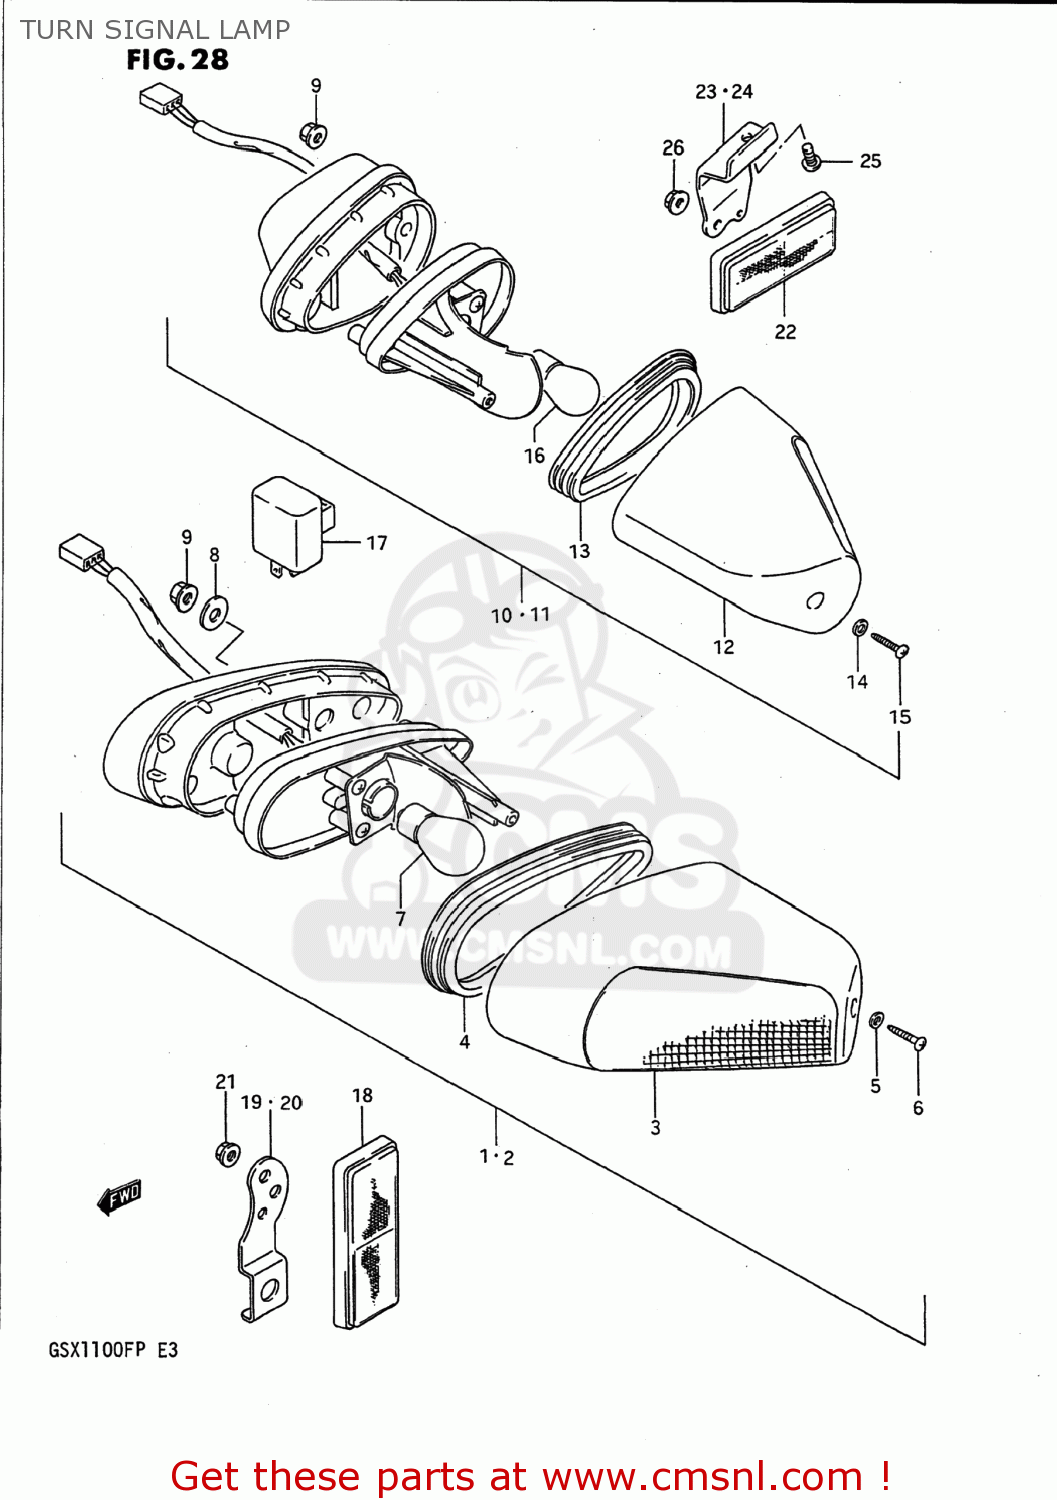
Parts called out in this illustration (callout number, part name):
1	LAMP ASSY,FR TURN SIGNAL,R
2	LAMP ASSY,FR TURN SIGNAL,L
3	LENS
4	GASKET (NAS)
5	GASKET (NAS)
6	SCREW 4X16
7	BULB(12V21/5W)
8	WASHER (6.5X18X1.6)
9	NUT 6MM
10	LAMP ASSEMBLY,REAR TURN SIGNAL
11	LAMP ASSEMBLY,REAR TURN SIGNAL
12	LENS
13	GASKET (NAS)
14	GASKET (NAS)
15	SCREW 4X16
16	BULB(12V21W)
17	RELAY ASSEMBLY,TURN SIGNAL
18	REFLEX REFLECTOR,FR SIDE
19	BRACKET,FRONT SIDE,REAR
20	BRACKET,FR SIDE RR,L
21	NUT ,5MM
22	REFLEX REFLECTOR,RR
23	BRACKET,RR SIDE RR,R
24	BRACKET,RR SIDE RR,L
25	SCREW
26	NUT ,5MM
